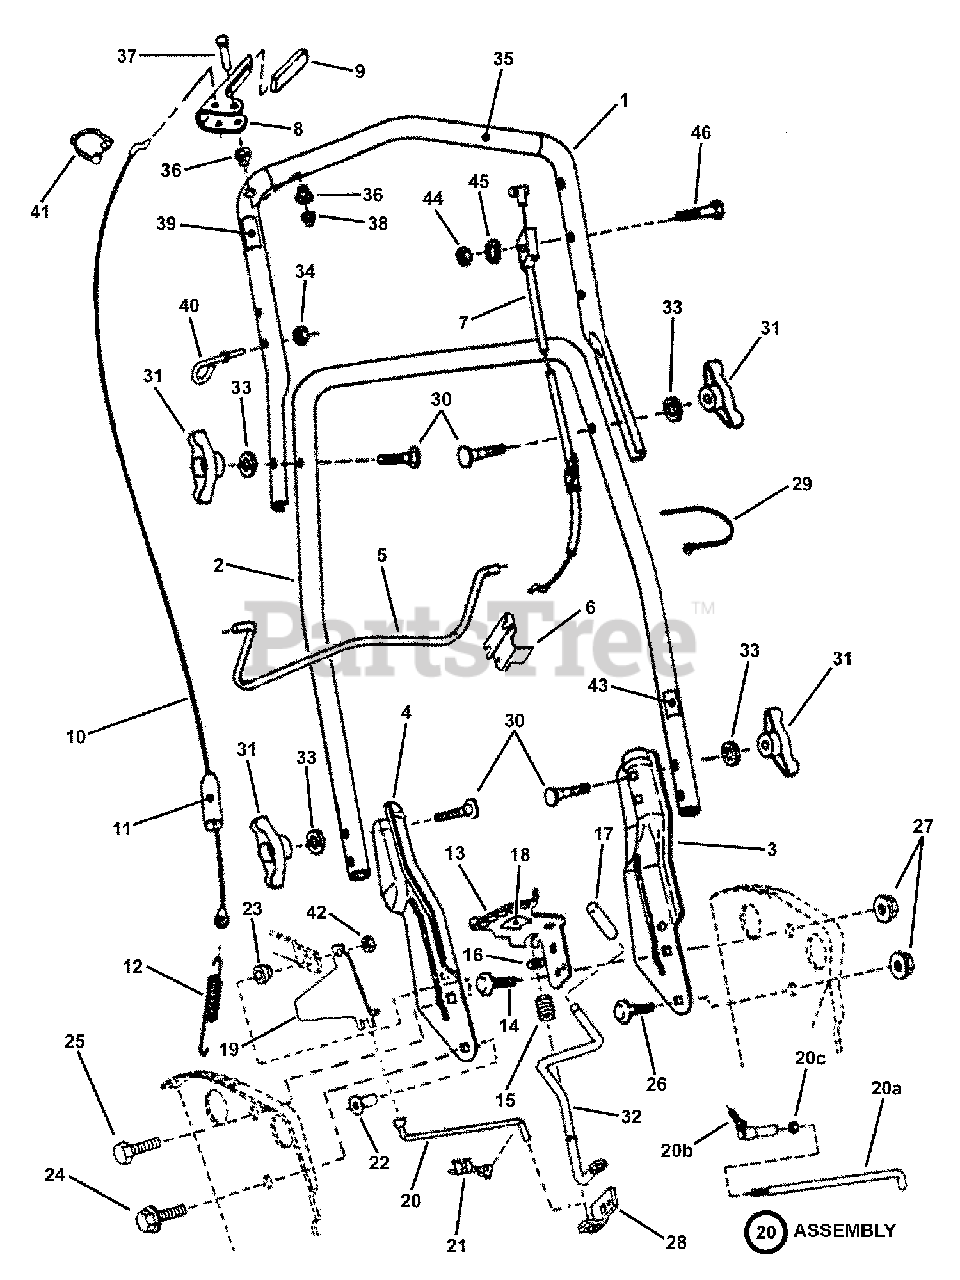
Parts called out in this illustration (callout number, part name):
1	HANDLE, Upper
2	HANDLE, Middle- 1990
3	HANDLE, Lower Left Hand
4	HANDLE, Lower Right Hand
5	BAIL, Blade Control
6	CLIP, Blade Control
7	CABLE, Blade Control (49-1/4" long)
8	HANDLE, Wheel Drive
9	GRIP, Wheel Drive Handle
10	CABLE, Clutch Pull (Z-Bend, 38-5/8" long)
11	COVER, Vinyl
12	SPRING, Clutch
13	SECTOR, Speed
14	BOLT, 5/16-18 x 1" Square Neck Carriage GR 5
15	SPRING, Speed Control
16	WASHER, 3/8" Flat
17	GRIP, Speed Control Handle
18	DECAL, Speed Select
19	GUIDE, Lower V-Belt
20	ROD, Transfer
21	CLIP, Transfer Rod 1/4"
22	TEE-NUT, 5/16-18
23	BUSHING, Differential
24	BOLT, 5/16-18 x 3/4" Hex Flange Lock GR5
25	SCREW, 5/16-24 x 1" Hex Head Cap GR5
26	BOLT, 5/16-18 x 5/8" Short Neck Carriage GR5
27	NUT, 5/16-18 Hex Flange Lock GR5
28	BRACKET, Speed Control Rod
29	WIRE TIE, 1.29" Long (Black)
30	SCREW, 5/16-18 x 1-7/8" Curved Head GR2
31	T-KNOB, 5/16-18 (BLACK)
32	LEVER, Speed Control
33	WASHER, 5/16" Internal Tooth Lock
34	NUT, 1/4-28 Hex GR5 or B
35	FOAM GRIP, .84 I.D. x 11" long
36	BUSHING
37	PIN, Clutch Handle
38	PUSH-NUT, 1/4" (for handle pin)
39	DECAL, Blade Control (Right Hand Side)
40	GUIDE, Rope
41	CLAMP, 7/8" Double Cable
42	NUT, 5/16-24 Hex Center Lock GR5
43	DECAL, Shift Warning
44	NUT, 1/4-20 Hex
45	WASHER, 1/4" Internal Tooth Lock
46	SCREW, 1/4-20 x 1-3/4" Hex Head Cap GR5
